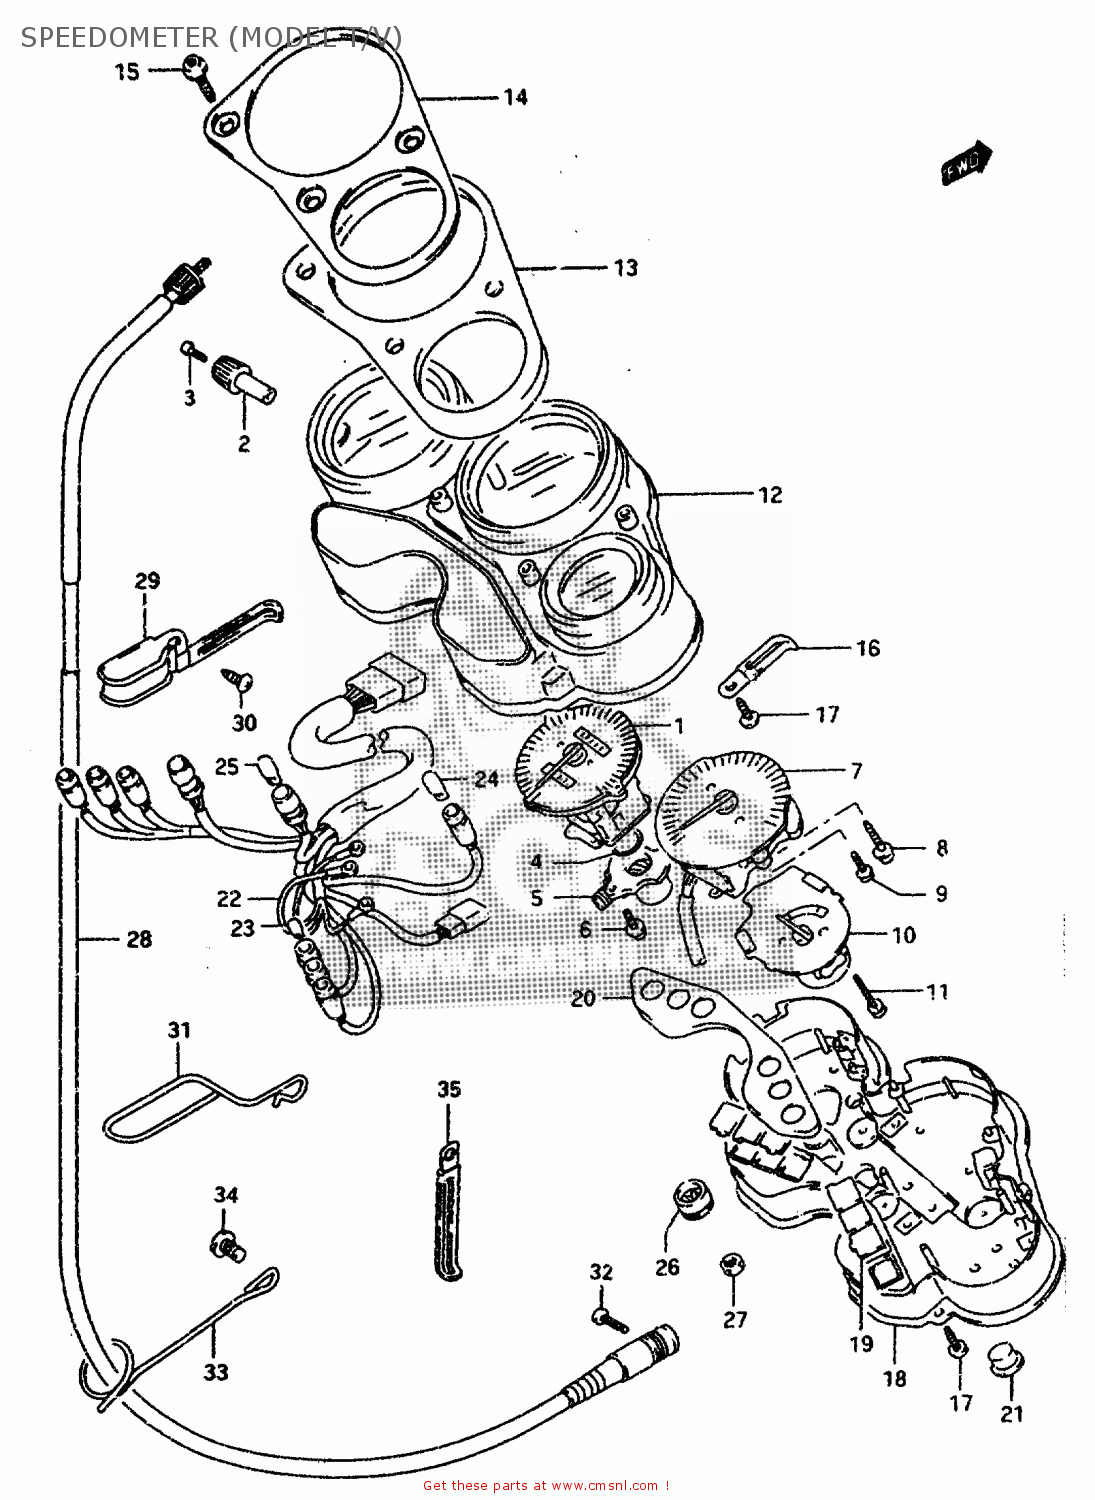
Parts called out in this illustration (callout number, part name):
1	SPEEDOMETER (KILO)
2	KNOB,TRIP
3	SCREW(2X6)
4	O RING
5	BOX,GEAR
6	SCREW
7	TACHOMETER
8	SCREW(4X22)
9	SCREW
10	METER,TEMPERATURE
11	SCREW(3X22)
12	HOOD
13	CUSHION
14	PANEL,METER
15	SCREW
16	CLAMP(L:45)
17	SCREW
18	CASE,METER
19	LENS SET
20	PANEL
21	CAP
22	SOCKET
23	BULB(12V3W,T6.5)
24	BULB(12V1.7W,T6.5)
25	BULB(12V1.7W,T10,WB121)
26	CUSHION,METER
27	NUT
28	CABLE ASSY,SPEEDOMETER
29	GUIDE,METER CABLE NO.1
30	SCREW 5X8
31	GUIDE, CABLE NO.2
32	SCREW
33	WASHER (6.5X20X1.6)
34	SCREW 6X10
35	NUT
36	CABLE ASSY,SPEEDOMETER
37	GUIDE,SPEEDOMETER CABLE
38	SCREW
39	NUT
40	GUIDE,SPEEDOMETER CABLE,R
41	SCREW
42	SCREW
